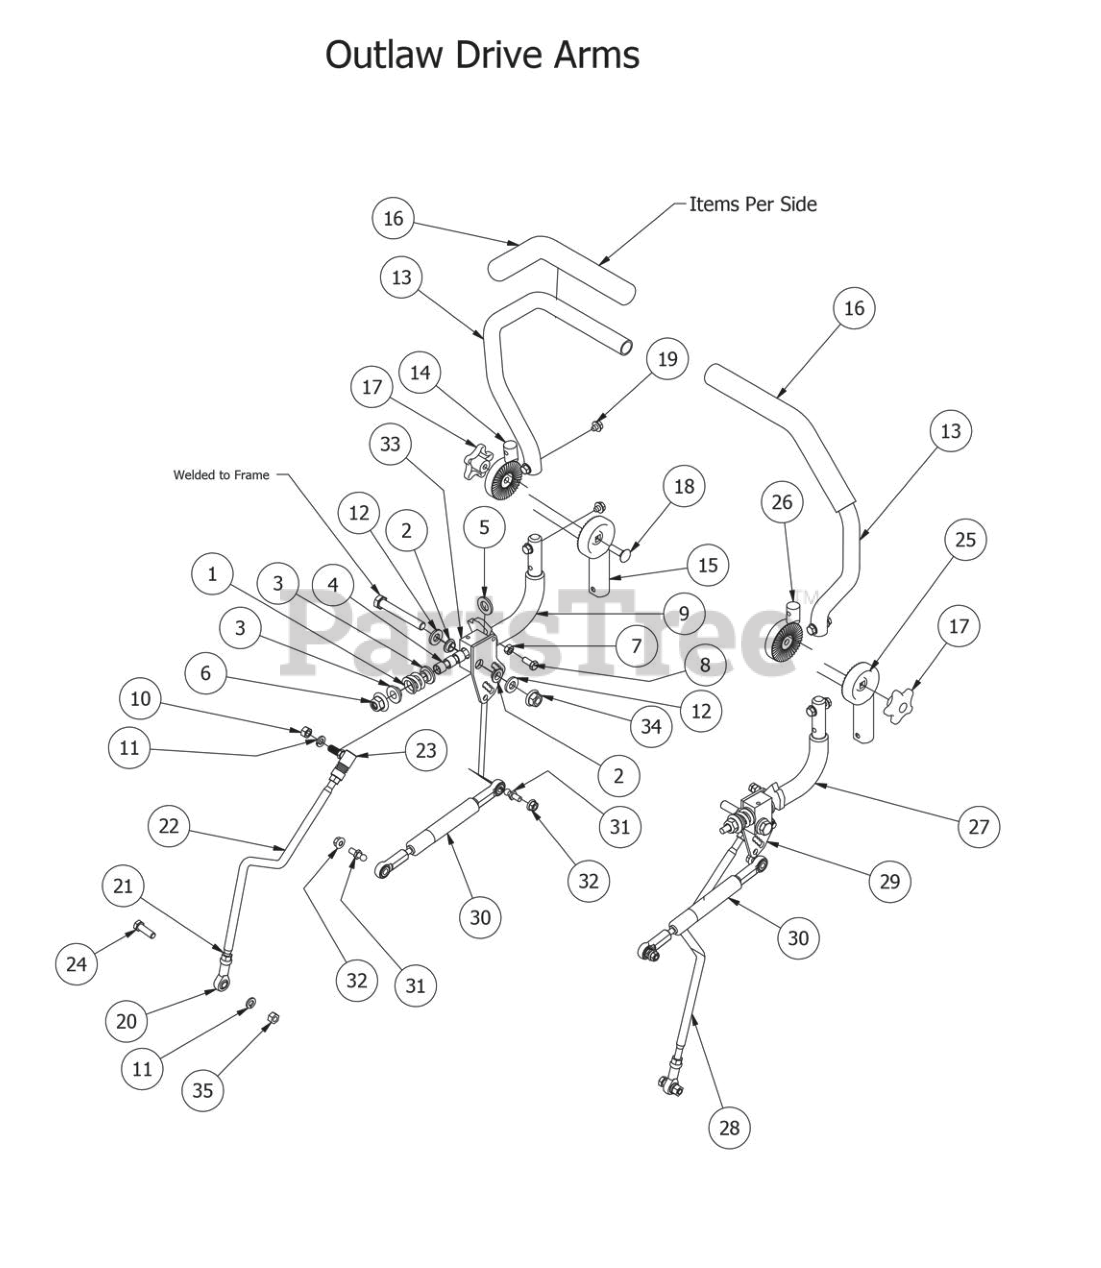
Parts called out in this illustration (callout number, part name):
1	Drive Lever Spring
2	Bushing for 2012 Drive Arms
3	.515 ID Nylon Shoulder Washer
4	.507 ID Nylon Bushing
5	.635 ID Plastic Washer
6	1/2-13 Nylon Flange Nut-Orange
8	5/16" x 3/4" Hex Bolt
9	Steering Arm Elbow - Left
10	3/8" Fine Threaded Jam Nut
11	3/8" Lock Washer
12	.505x1x .125 Oil Impregnated washer
13	Upper Tube-Adjustable Steering
14	Upper adjuster-Steering Arm- Left
15	Lower Adjuster - Steering Arm- Left
16	Black Steering Grip
17	Black Knob for Adjustable Steering Arm
18	3/8" x 1 1/4" Carriage Bolt
19	5/16-18 1/2 HWH Bolt-Steering
20	Spherical Rod End - Outlaw
21	3/8" Fine Threaded Jam Nut
22	Push Rod for Outlaw - Left
23	Quick Release Ball Joint
24	3/8" x 1 1/4" Hex Bolt
25	Lower Adjuster - Steering Arm- Right
26	Upper Adjust Steering Arm- Right
27	Steering Arm Elbow - Right
28	Push Rod for Outlaw - Right
29	2013 Drive Lever Housing (Right)
30	Steering Damper For Outlaw
31	10mm Damper Ball Stud-Steering
32	5/16" Flange Nut
33	2013 Drive Lever Housing (Left)
34	1/2-13 Hex Flange (GR.G) ZC
35	3/8-16 Hex Nuts Zinc
